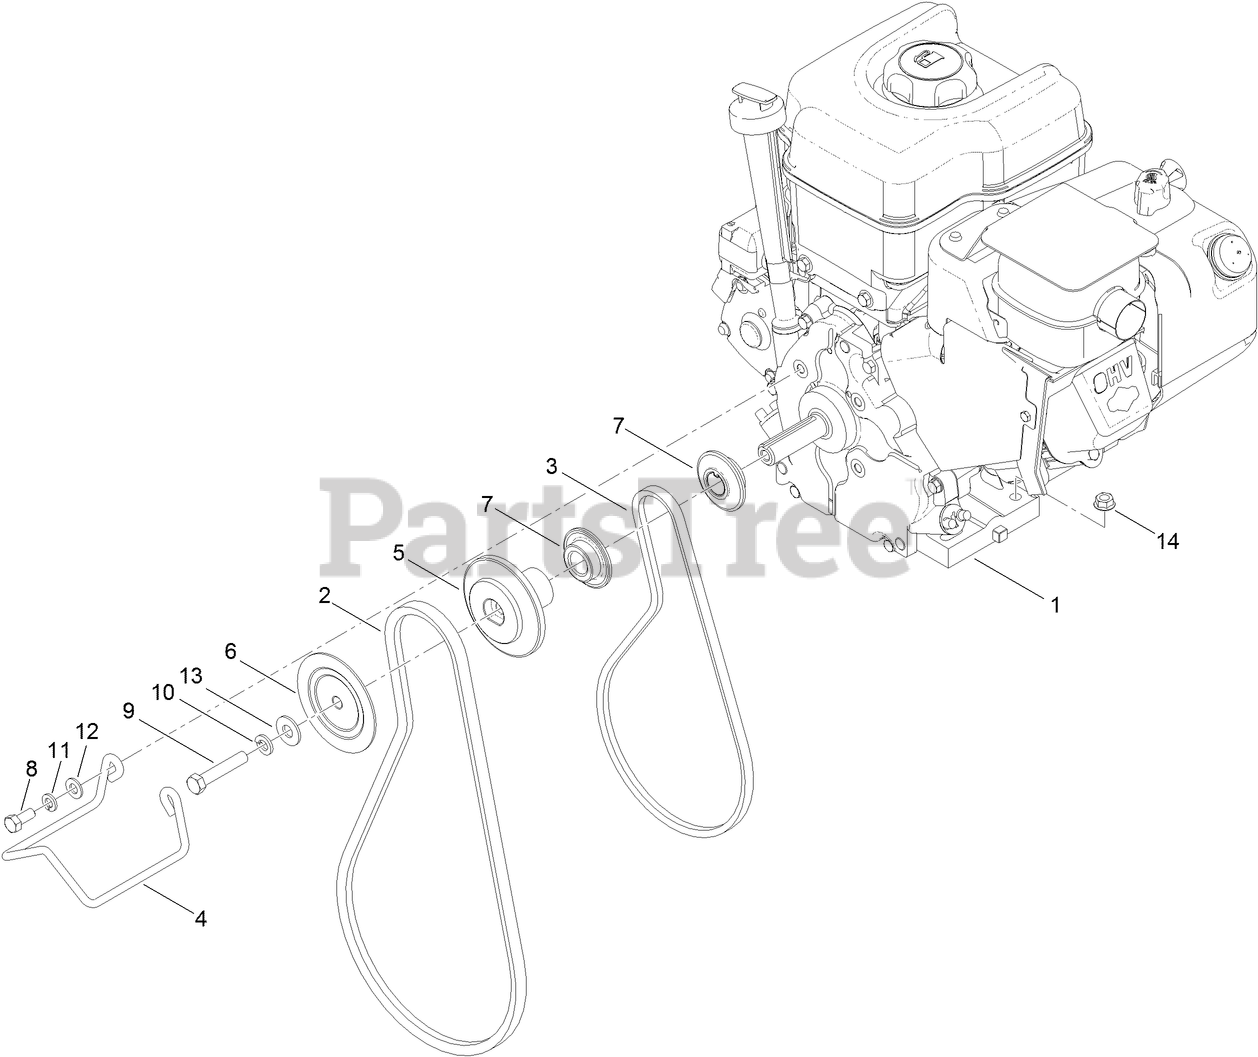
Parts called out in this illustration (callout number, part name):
2	BELT-V
3	BELT-V
5	PULLEY-AUGER, REAR
6	PULLEY-AUGER, FRONT
7	PULLEY-TRACTION
8	SCREW-HH
9	SCREW-HH
10	WASHER-LOCK
11	WASHER-LOCK
12	WASHER-PLAIN
13	WASHER-FLAT
14	NUT-HF
